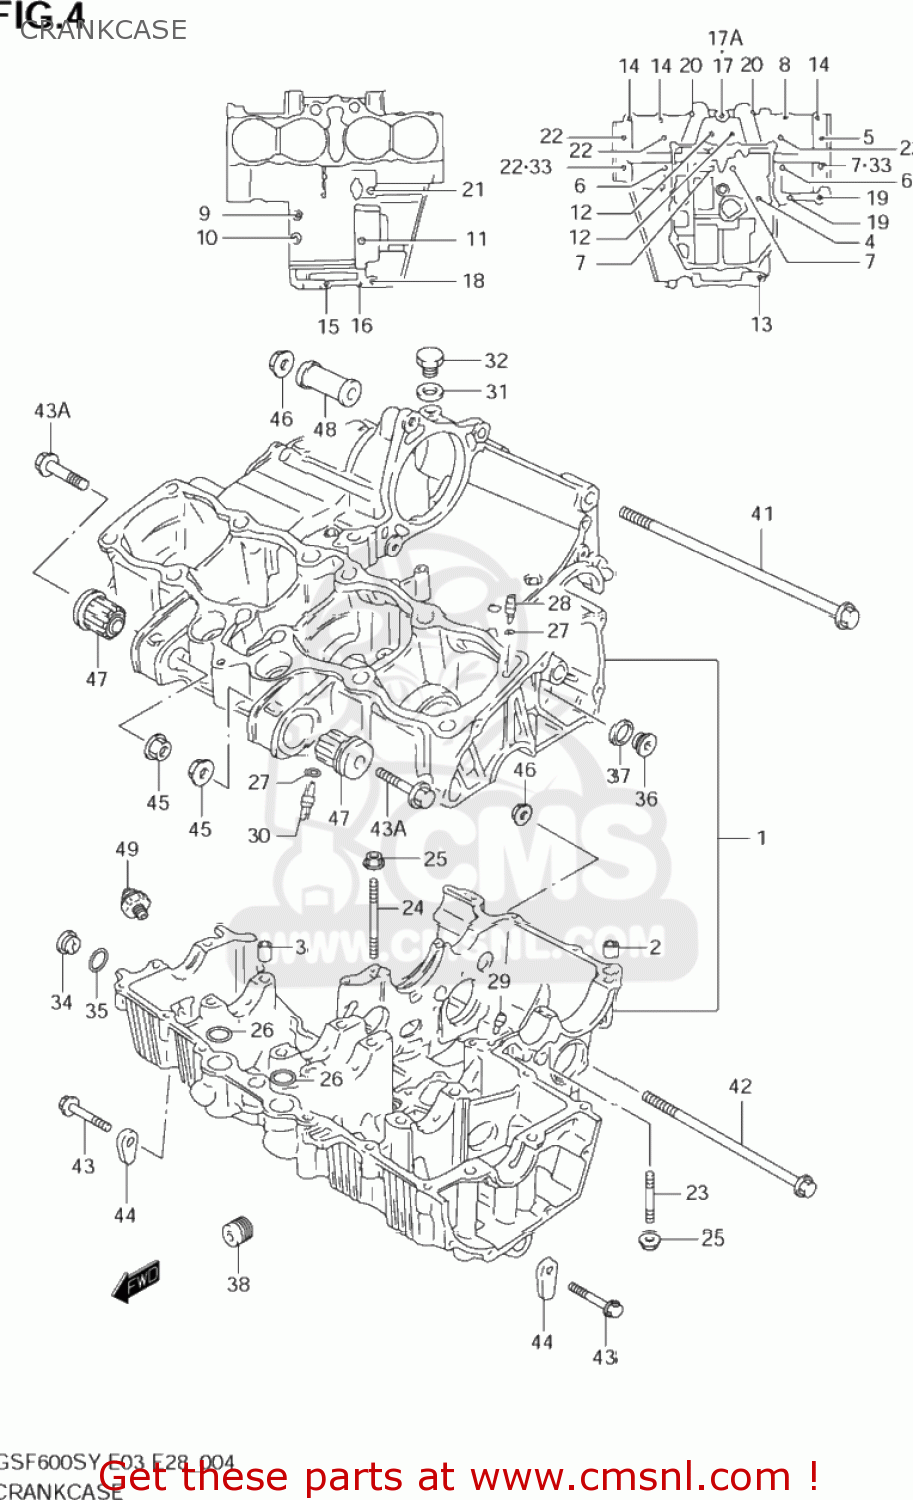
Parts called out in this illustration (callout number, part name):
1	CRANKCASE SET
2	PIN(10.4X13X22)
3	PIN(8.4X11X20)
4	BOLT(6X105)
5	BOLT(8X105)
6	BOLT(8X125)
7	BOLT(8X115)
8	BOLT
9	BOLT
10	BOLT,CL.COVER
11	BOLT
12	BOLT
13	BOLT
14	BOLT
15	BOLT
16	BOLT
17	BOLT
17A	GASKET(5.8X13X1.2) (NAS)
18	BOLT
19	BOLT, HYDRAULIC UNIT NO.2
20	BOLT
21	BOLT
22	BOLT(8X95)
23	STUD BOLT
24	STUD BOLT
25	NUT
26	O RING(D:2.5,ID:21)
27	O RING(D:1.2,ID:4)
28	JET,AIR
29	JET
30	JET(13)
31	GASKET(12.1X16.2X3.7) (NAS)
32	PLUG(12X9)
33	GASKET(8.5X17X2.3) (NAS)
34	PLUG
35	O RING(D:2.4,ID:16.8)
36	PLUG
37	GASKET(13.8X18.8X4.8) (NAS)
38	UNION,OIL STAND
39	PLATE,CRANK THRUST
40	PLATE,CRANK THRUST
41	BOLT(10X180)
42	BOLT(10X130)
43	BOLT
43A	BOLT
44	NUT
45	NUT
46	NUT
47	BUSH,ENGINE MOUNTING
48	SPACER,ENGINE MOUNT(L27)
49	SWITCH ASSY,OIL PRESSURE
